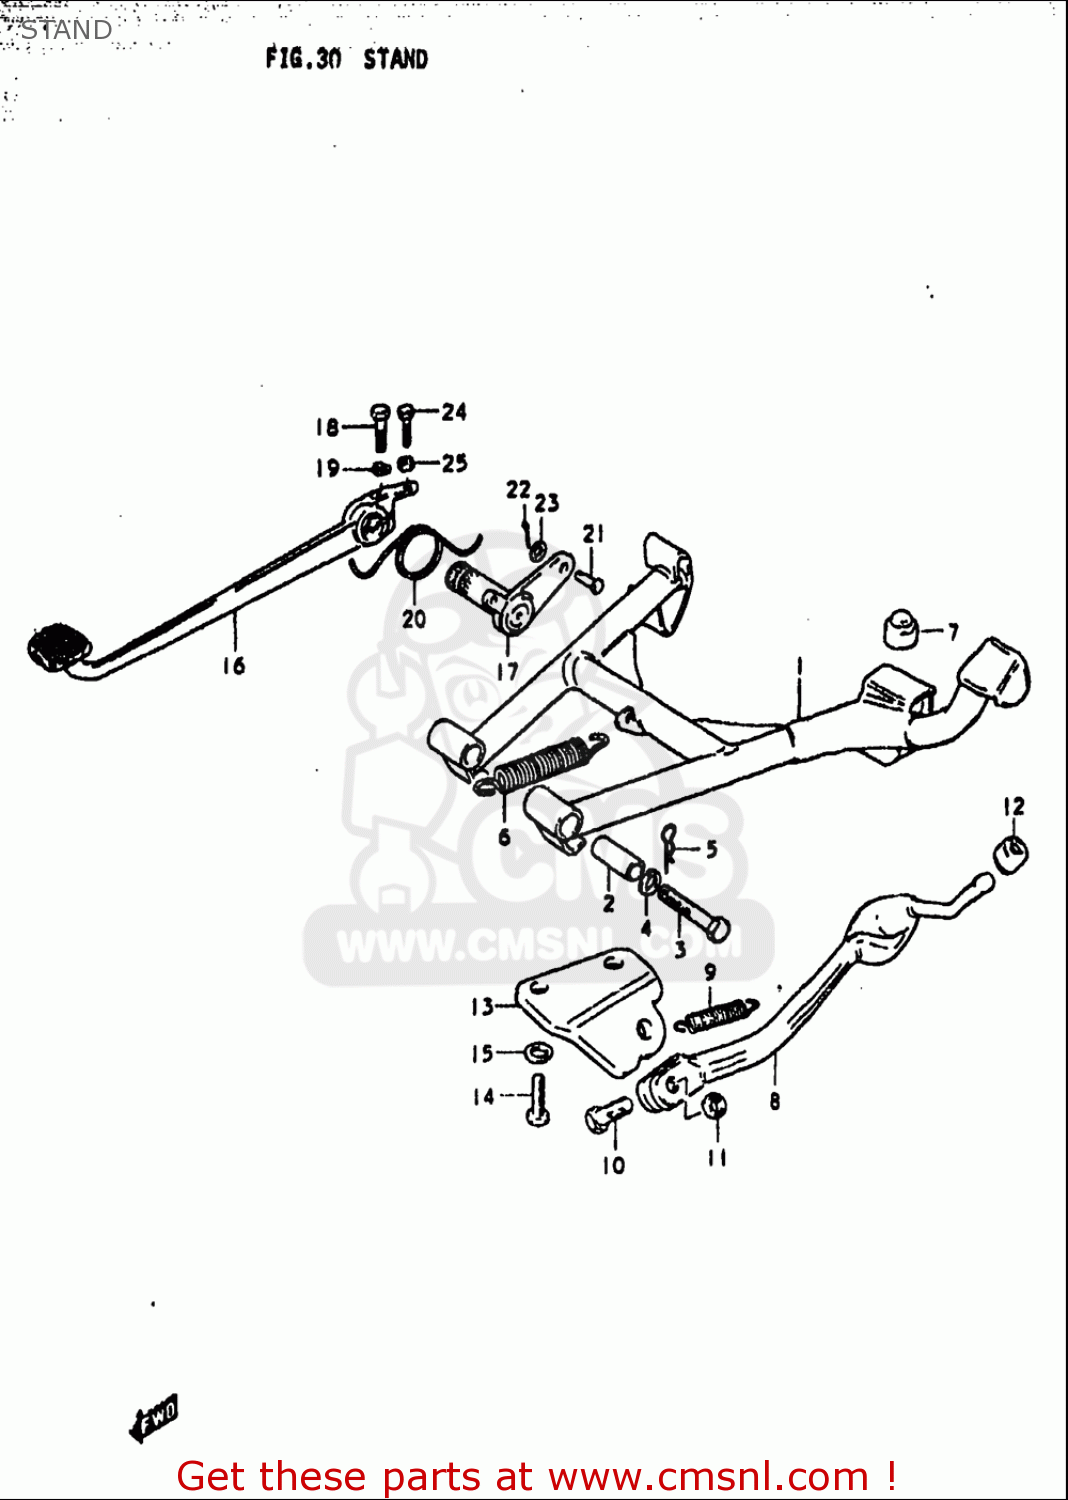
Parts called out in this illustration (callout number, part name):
2	SPACER(10X16X38.8)
3	BOLT(10X65)
4	WASHER,LOCK
5	CLIP
6	SPRING
7	CUSHION
8	STAND,PROP
9	SPRING
10	BOLT(10X30)
11	NUT
12	CUSHION
14	BOLT(10X27)
15	WASHER,LOCK
18	BOLT
19	WASHER,LOCK
20	SPRING
21	PIN
22	PIN
23	WASHER
24	BOLT
25	NUT
